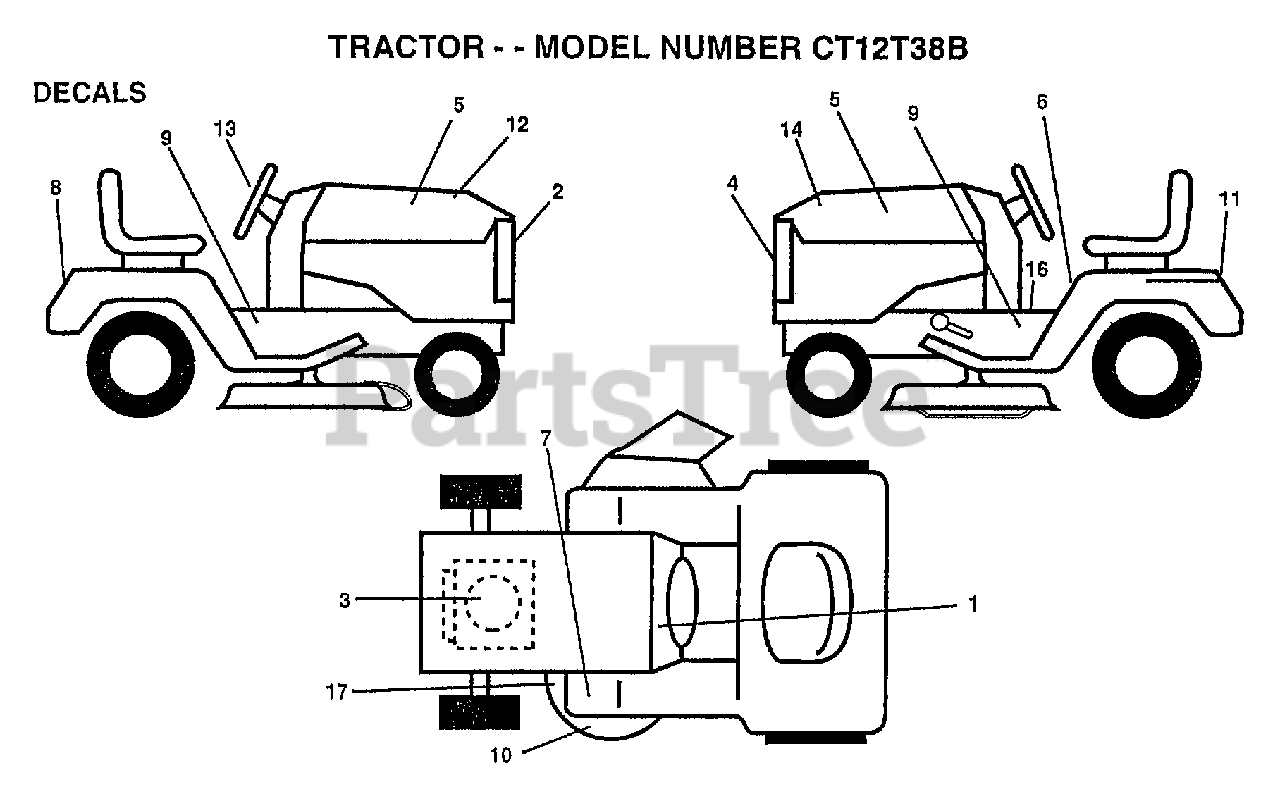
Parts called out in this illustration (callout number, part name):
1	"DECAL-OPER,GEAR D"
2	GRILL DECAL
3	DECAL, HP, ENGINE
5	DECAL.HOOD.INS.
6	"DECAL DANGER,FEND"
8	FENDER DECAL
9	DECAL CHASSIS SPEED DECK
11	DECAL.BATRY.3-3908
12	DECAL HOOD RH RLY
13	"DECAL,STR WHL"
14	DECAL HOOD LH RLY
16	DECAL BRAK PARK
17	DECAL
